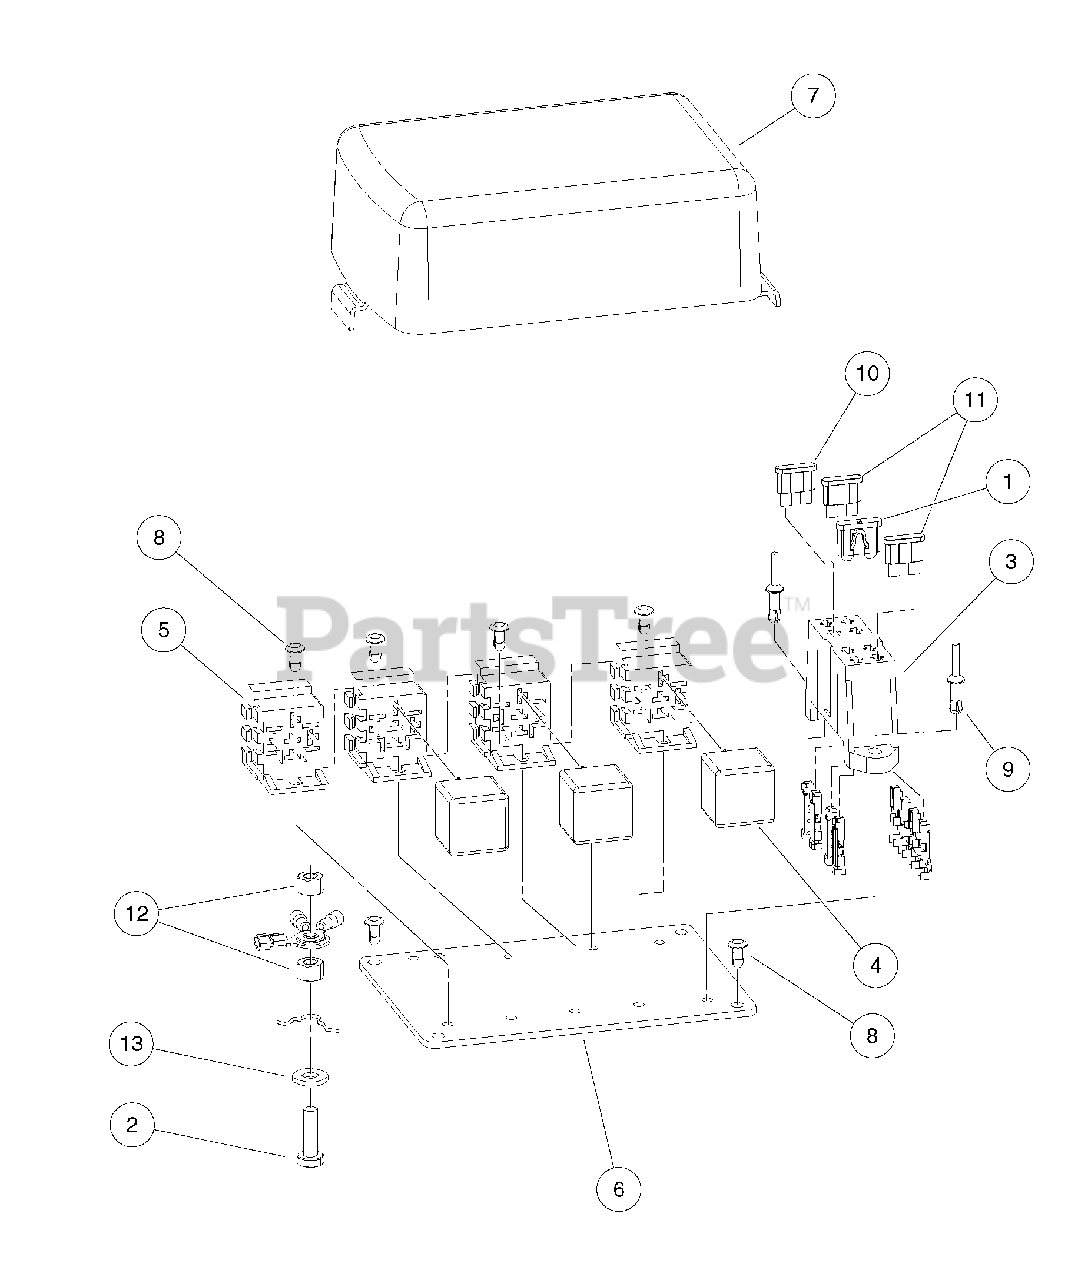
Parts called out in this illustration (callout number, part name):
1	Fuse, 10-Amp
2	Screw, 1/4-20 X .88 Hex Hd Cap
3	Fuse Block
4	Relay, Mini ISO, SPDT
5	Connector, Relay
6	Plate, Electrical
7	Cover, Electrical
8	Fastener, Push-in
9	Rivet, Drive
10	Fuse, 25-Amp
11	Fuse, 30-Amp
12	Locknut, 1/4-20 Dimpled
13	Washer, 1/4 Type A Narrow Flat
